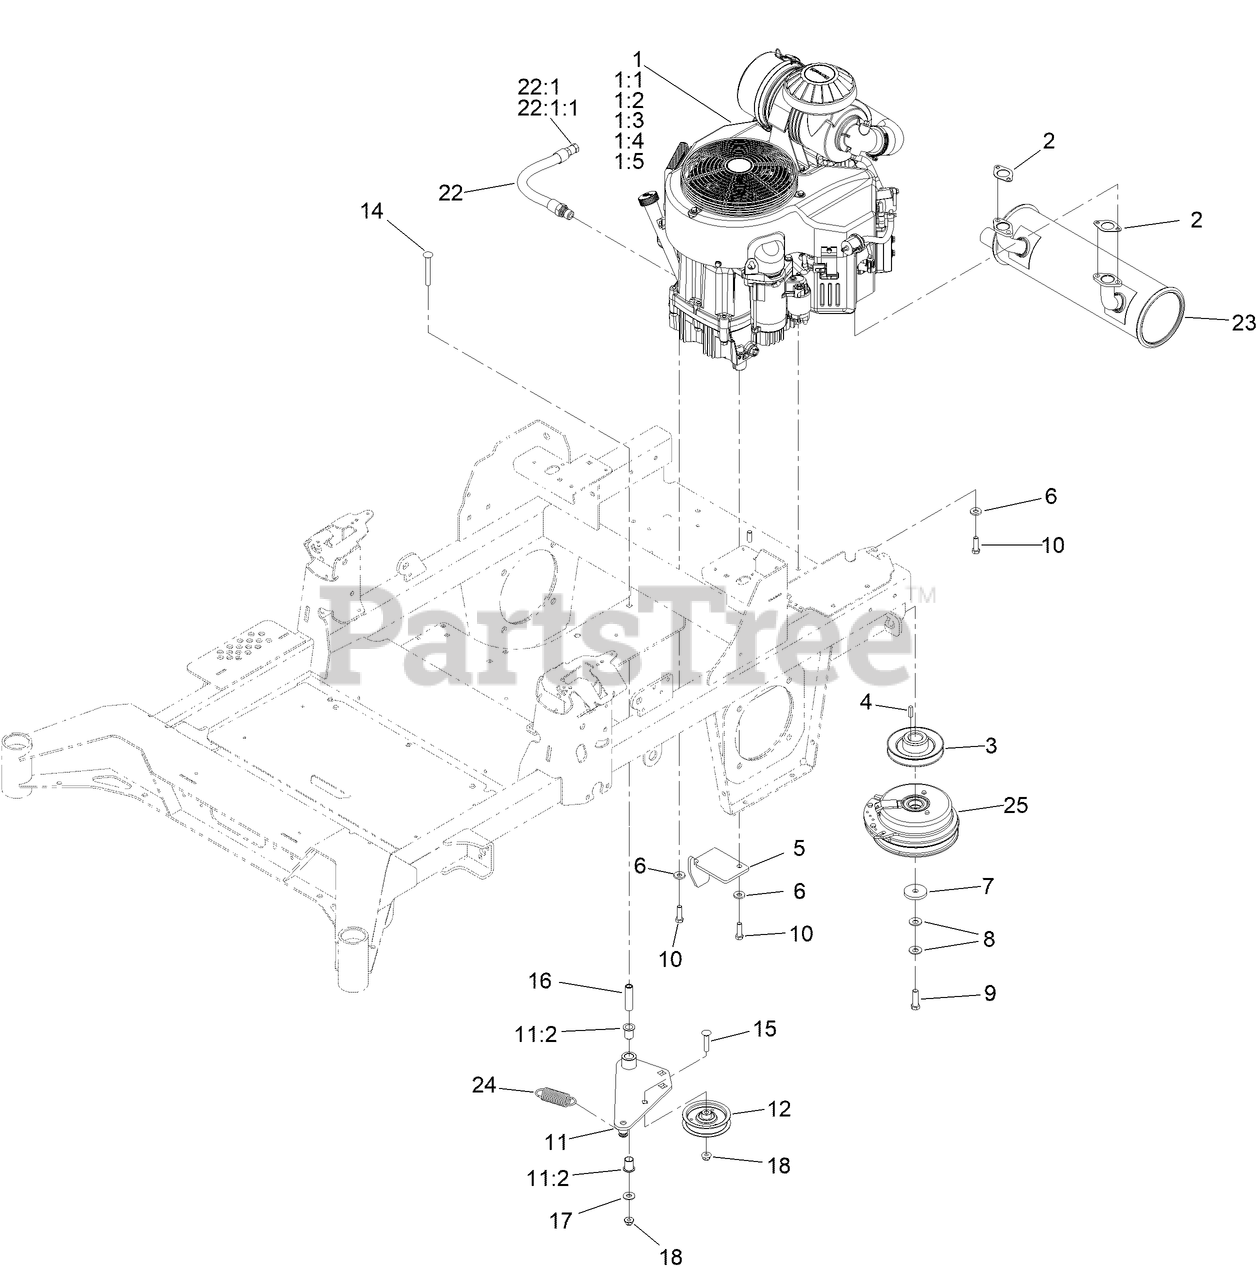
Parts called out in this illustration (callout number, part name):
1	ENGINE-KAWASAKI
1:1	FILTER-OIL
1:2	FILTER-FUEL
1:3	ELEMENT-FILTER, AIR (INNER)
1:4	ELEMENT-FILTER, AIR (OUTER)
1:5	SPARK PLUG
2	GASKET-EXHAUST
3	SHEAVE, W/HUB
5	ANCHOR-CLUTCH
6	WASHER-BELLEVILLE
7	WASHER-CLUTCH
8	WASHER-SPRING
9	SCREW-HH, W/LOCTITE
10	SCREW-HH
11	IDLER ARM ASM
11:2	BUSHING-FLANGE
12	PULLEY-IDLER, FLAT
14	SCREW-CARR
15	SCREW-CARR
16	BUSHING, IDLER PIVOT
17	WASHER-FLAT
18	NUT-HF, NI
22	ENGINE OIL DRAIN HOSE ASM
22:1	PLUG-HH
22:1:1	O-RING
23	MUFFLER
24	SPRING-IDLER
25	CLUTCH
